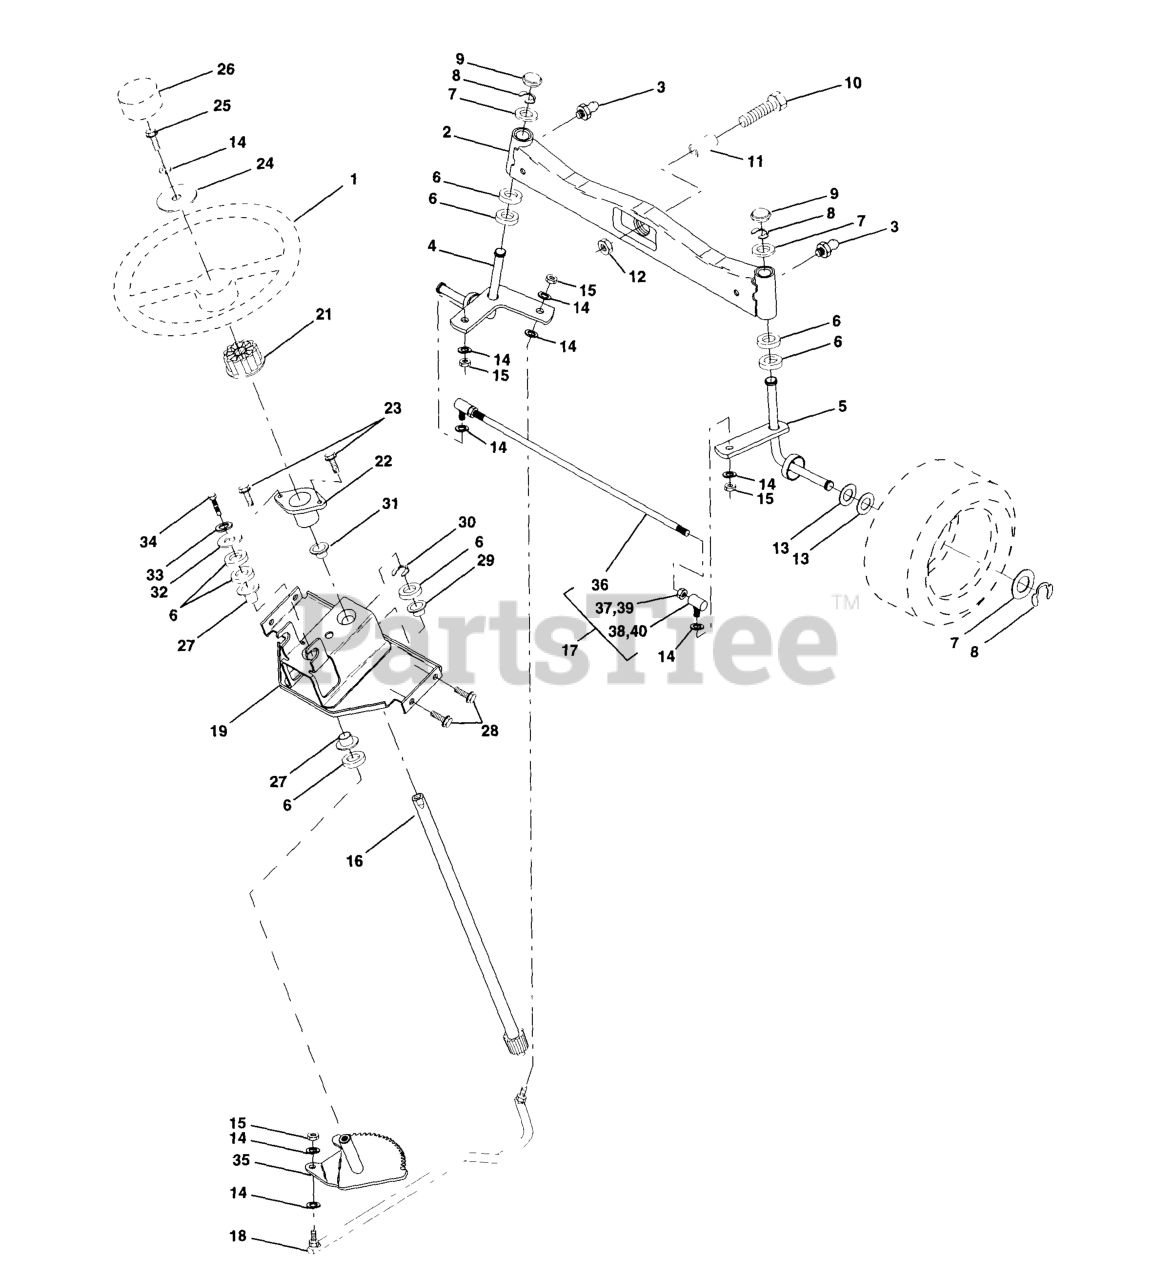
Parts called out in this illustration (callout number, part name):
1	STEERING WHEEL
2	FRONT AXLE ASSY
3	ZERK M
4	SPINDLE ASSY LH
5	SPINDLE ASSY RH
6	BEARING RACE
9	CAP.SPINDLE.BLACK
10	Bolt, Fin Hex 5/8-11 x 2-3/4
11	TUBE, PIVOT AXLE
12	NUT-LOC,FLANGE LT
14	WASHER, LOCK 3/8
15	NUT
16	SHAFT ASM, STEERING
17	ROD ASSY/TIE BALL
18	DRAGLINK-BALL JOINT SOLID
19	SUPPORT ARM, STEERING VGT
21	ADAPTER LT
22	BUSHING LT
23	SCREW LT
24	WASHER T
25	BOLT
26	INSERT,STR WHEEL
27	BRNG T
28	SCREW
29	BEARING-FLANGE GT
30	Ring, Klip Truarc #5304-75
31	BUSHING.NYLINER.
33	WASHER.LOCK.HVY.HLCL.SPR.5/16
34	BOLT
35	GEAR.ASM.SECTOR.
36	TIE ROD
38	JOINT
